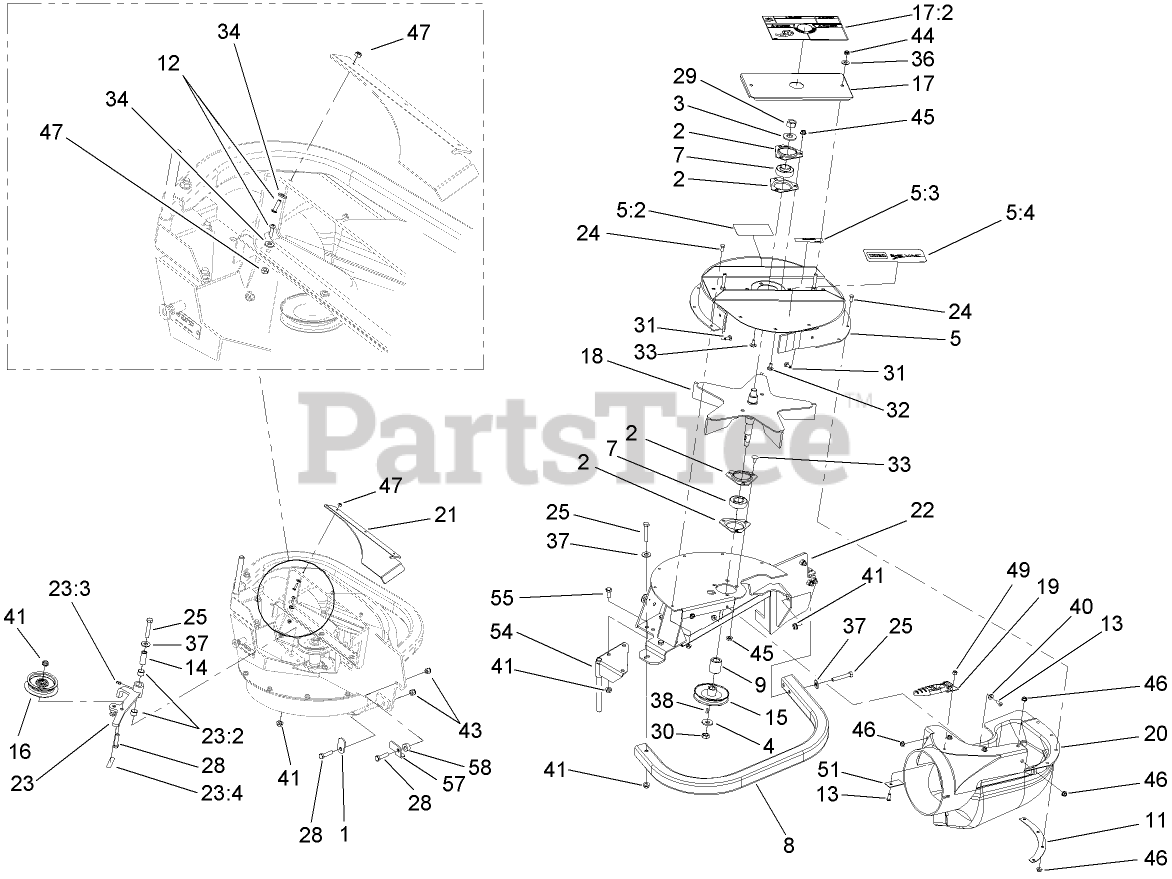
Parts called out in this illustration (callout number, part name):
1	LATCH-CATCHER, GRASS
2	HOUSING-FLANGE
3	WASHER-SPRING
4	WASHER-SPRING
5	UPPER HOUSING ASM
5:2	DECAL-WARNING
5:3	DECAL-COVER, MISSING
7	BEARING
9	SPACER
11	PLATE-BACKING, BLOWER
12	SCREW-HSBH
13	SCREW-HSBH
14	BUSHING
15	SHEAVE
16	IDLER-FLAT
17	COVER-BEARING
17:2	DECAL-WARNING
18	IMPELLER
19	LATCH-RUBBER
20	CHUTE-BLOWER
21	PLATE-BOTTOM
22	BLOWER MOUNT ASM
23	IDLER ARM ASM
23:2	BUSHING
23:3	FITTING-GREASE
23:4	DECAL-WARNING
24	SCREW-HH
25	SCREW-HH
28	SCREW-HH
29	NUT-HEX
30	NUT-JAM
31	BOLT-CARR
32	SCREW-CARR
33	SCREW-CARR
34	WASHER-FLAT
36	WASHER-FLAT
37	WASHER-FLAT
38	KEY-WOODRUFF
40	WASHER-FLAT
41	NUT-HHF, WHIZ
43	NUT-LOCK, NI
44	NUT-LOCK, NI
45	NUT-HF
46	NUT-HF
47	NUT-LOCK, NI
49	NUT-LOCK, NI
51	PLATE-BACKING
54	PIN-MOUNT
55	SCREW-HH
57	LATCH-STOP
58	SPACER
